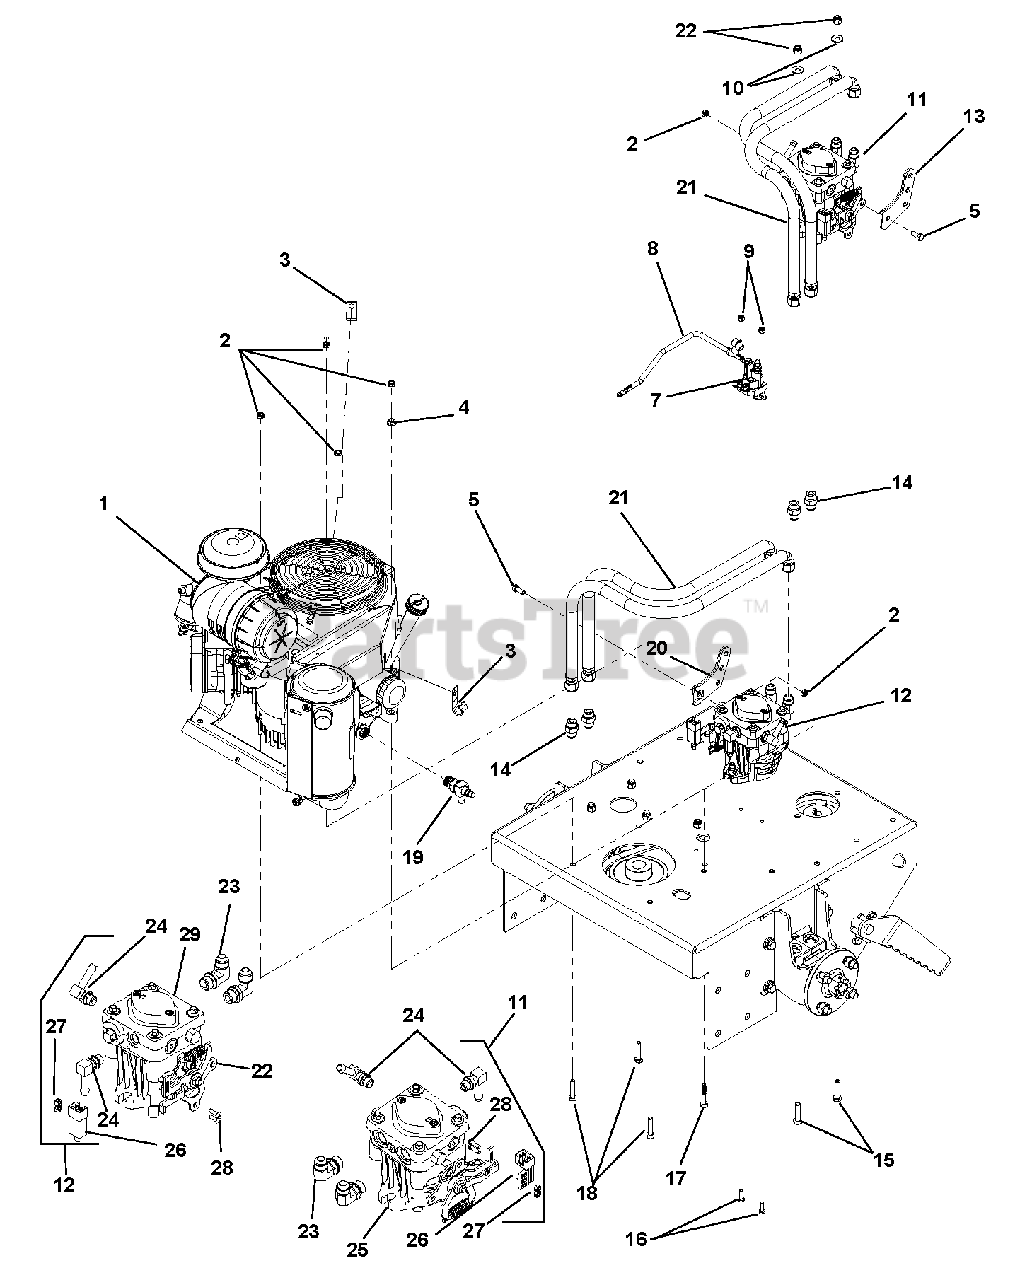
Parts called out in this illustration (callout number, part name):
1	ENGINE, KAWASAKI 19HP FH580V
2	LOCKNUT, 5/16-18 NYLOC Y
3	P-CLIP, .500 INSULATED
4	LOCKNUT, 5/16-18 WHIZ Y
5	BOLT, 5/16-18 X .750 HEX 5 Y
6	BOLT, 3/8-16 X 1.00 HEX 5 Y
7	SOLENOID, 12 V STARTER
8	CABLE, 12" STARTER
9	LOCKNUT, 1/4-20 NYLOC Y
10	WASHER, .313 REG FLAT Y
11	ASSY, LH PUMP WALKBEHIND (INCLUDES ITEMS 23, 24, 26 - 28)
12	ASSY, RH PUMP WALKBEHIND (INCLUDES ITEMS 23 - 29)
13	WLDT, CSWS LH HYDRO PUMP ARM
14	FITTING, STRAIGHT
15	BOLT, 3/8-16 X 1.50 HEX 5 Y
16	BOLT, 1/4-20 X .750 HEX 5 Y
17	BOLT, 5/16-18 X 1.75 HEX 5 Y
18	BOLT, 5/16-18 X 1.50 HEX 5 Y
19	OIL DRAIN FITTING
20	WLDT, CSWS HYDRO PUMP ARM
21	HOSE, HYD 1/2 X 26 1/2 EZFLEX
22	LOCKNUT, 3/8-16 NYLOC Y
23	FTG, ADP JIC-ORB 6801-08-08
24	FTG, 90 9/16 MOR X 3/8 HOSE
25	PUMP, HYD - PG-1HDA-D41X-XXXX RH
26	SWITCH, PLUNGER DP - N.O. - N.C.
27	LOCKNUT, 10-24 NYLOC Y
28	SCREW, 10-24X.625 PAN PHL MACY
29	PUMP, HYD - PG-1HDA-D61X-XXXX LH
